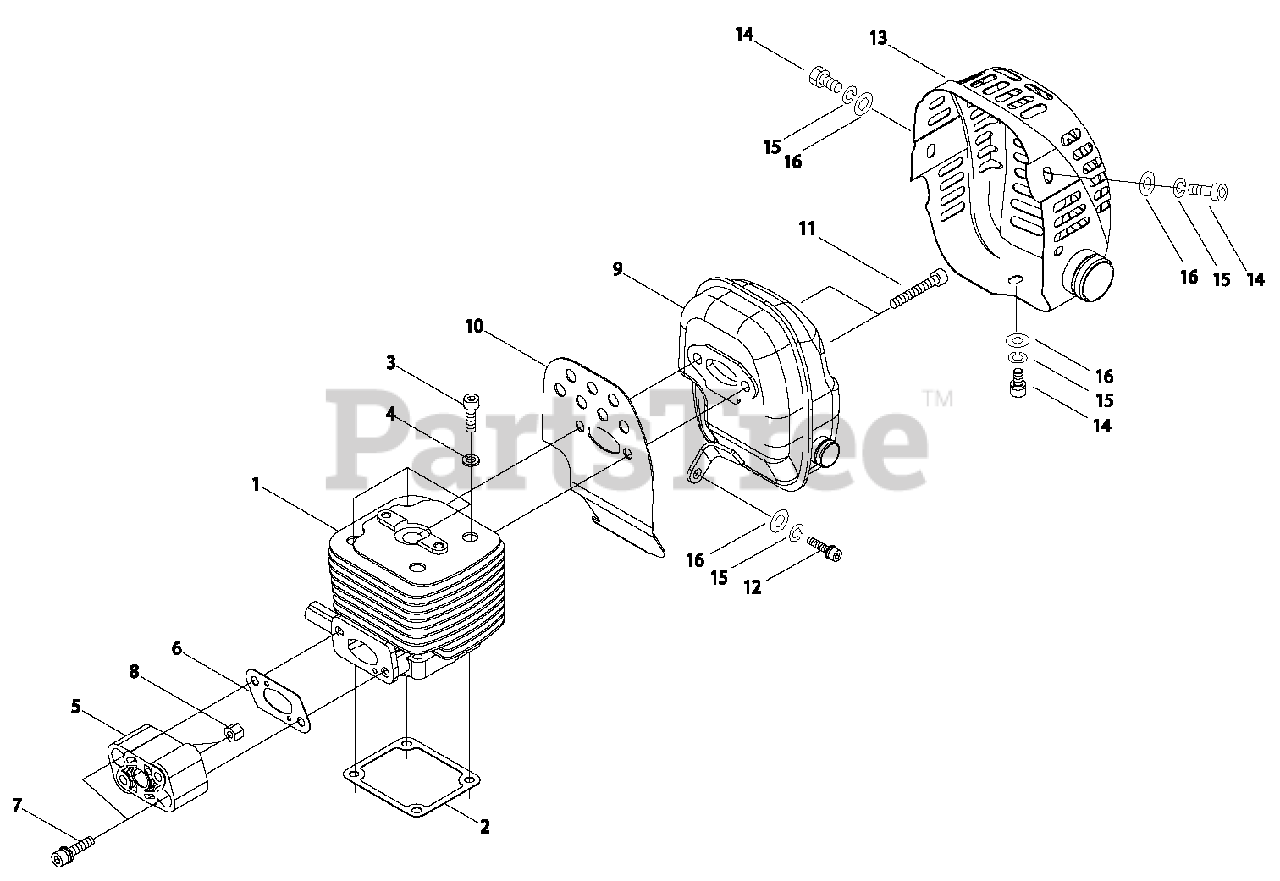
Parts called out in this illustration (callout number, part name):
1	CYLINDER
2	GASKET, CYLINDER
3	SCREW - 5X25
4	LOCKWASHER - 5
5	INSULATOR, INTAKE
6	GASKET, INTAKE
7	SCREW - 5X25
8	NUT
9	MUFFLER ASSY
10	SHIELD, EXHAUST
11	BOLT
12	SCREW
13	COVER, EXHAUST
14	SCREW - 5X10
15	LOCKWASHER - 5
16	WASHER - 5
